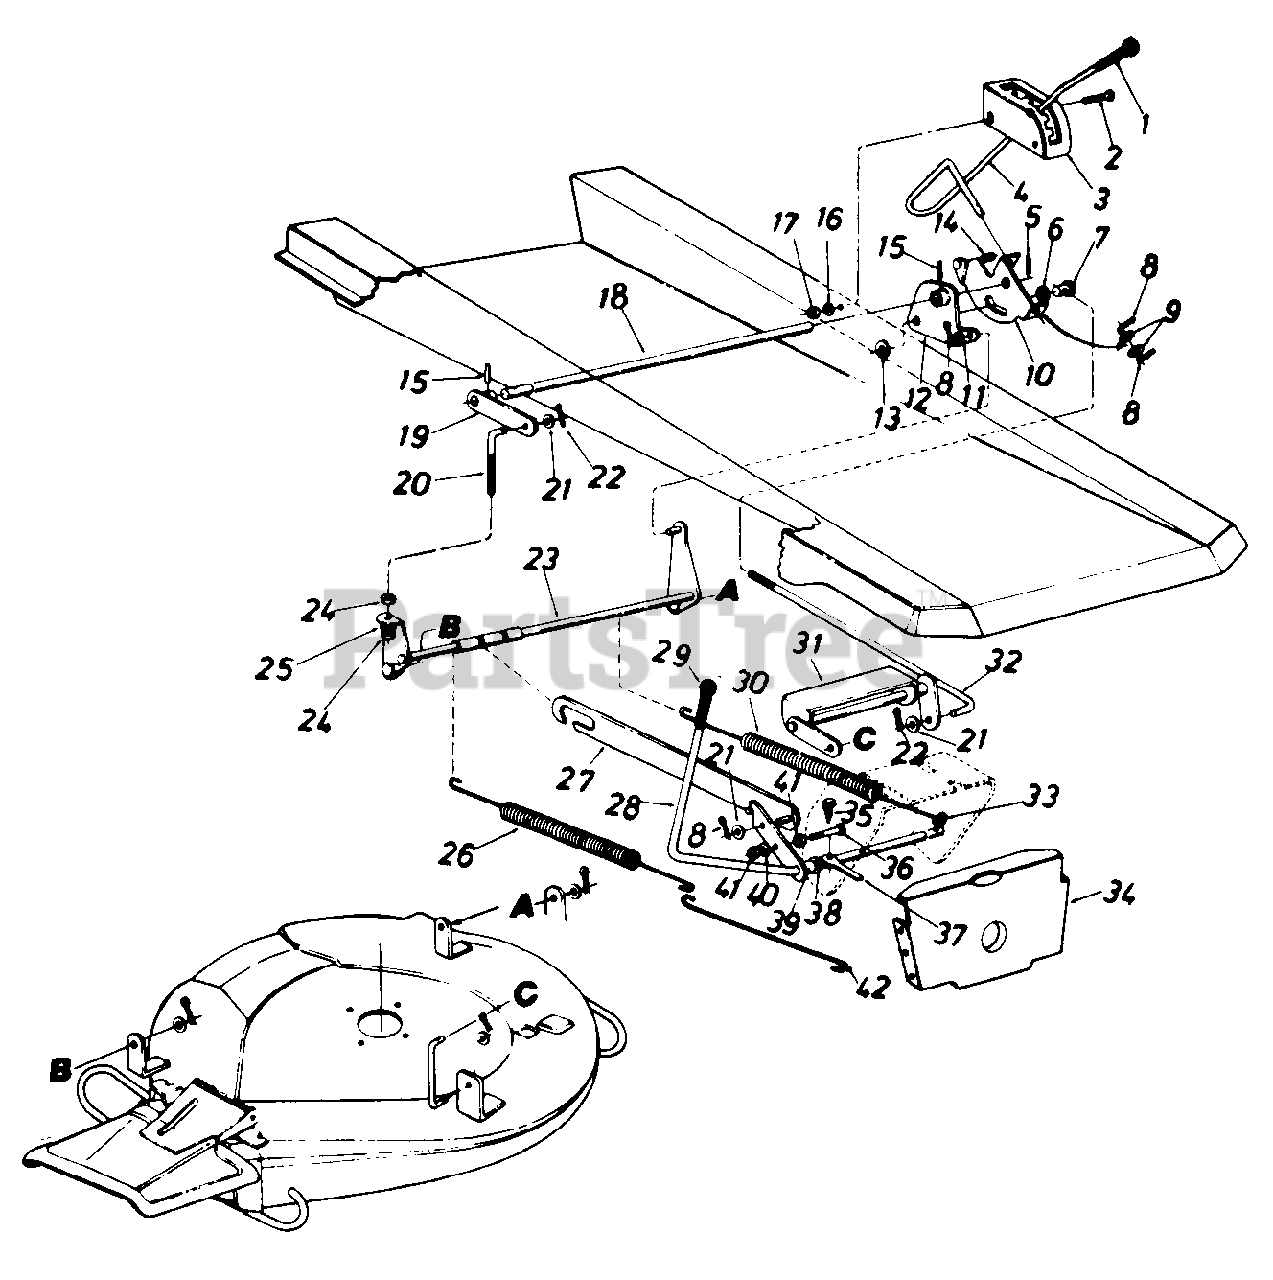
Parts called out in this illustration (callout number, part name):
2	Truss Mach. Scr. 5/16-18 x .75" Lg.
5	Spring Pin Spir. 3/16" Dia. x 1.50" Lg.
6	Fl-Wash. .385" I.D. x .87" O.D.
7	Adj. Ferrule Deck Lift Handle
8	Cotter Pin 1/8" Dia. x 1.00" Lg.
9	Fl-Wash. .531" I.D. x .930" O.D.
10	Deck Lift Handle Retainer Ass'y.
11	Fl-Wash. .385" I.D. x .87" O.D.
12	Deck Lift Brkt. Ass'y. L.H.
13	Fl-Wash. .635" I.D. x 1.04" O.D.
14	Compression Spring .50" Dia. x 1.0" Lg.
15	Spring Pin Spir. 1/4" Dia. x 1.50" Lg.
16	L-Wash. 5/16" I.D.
17	Hex Nut 5/16-18 Thd.
18	Rear Hgt. Adj. Shaft
19	Deck Lift Brkt. Ass'y. R.H.
20	Deck Adj. Scr. 3/8-16 Thd.
21	Fl-Wash. .385" I.D. x .87" O.D.
22	Intern. Cotter Pin 1/2" Dia.
23	Deck Link Ass'y. Rear
24	Hex Nut 3/8-16 Thd.
25	L-Wash. 3/8" I.D.
26	Extension Spring .73" O.D. x 13.84" Lg.
27	Deck Drive Control Bracket
28	Blade Engagement Lever Ass'y.
30	Extension Spring .73" O.D. x 1 3.89" Lg.
31	Deck Lift Ass'y. Front
32	Deck Lift Connecting Rod
33	Clevis Pin Special .250" Dia.
34	Pivot Bar Bracket
35	Hex TT-Tap Scr. 1/4-20 x .75"Lg.
36	Hex Bolt 5/16-18 x 1.50" Lg. (Grade 5)
37	Switch Actuator
38	Fl-Wash. .531" I.D. x .930" O.D.
39	Spacer .511" I.D. x .70" O.D. x.38" Lg.
40	L-Wash. 5/16" I.D.
41	Hex Nut 5/16-18 Thd.
42	Spring Hook
